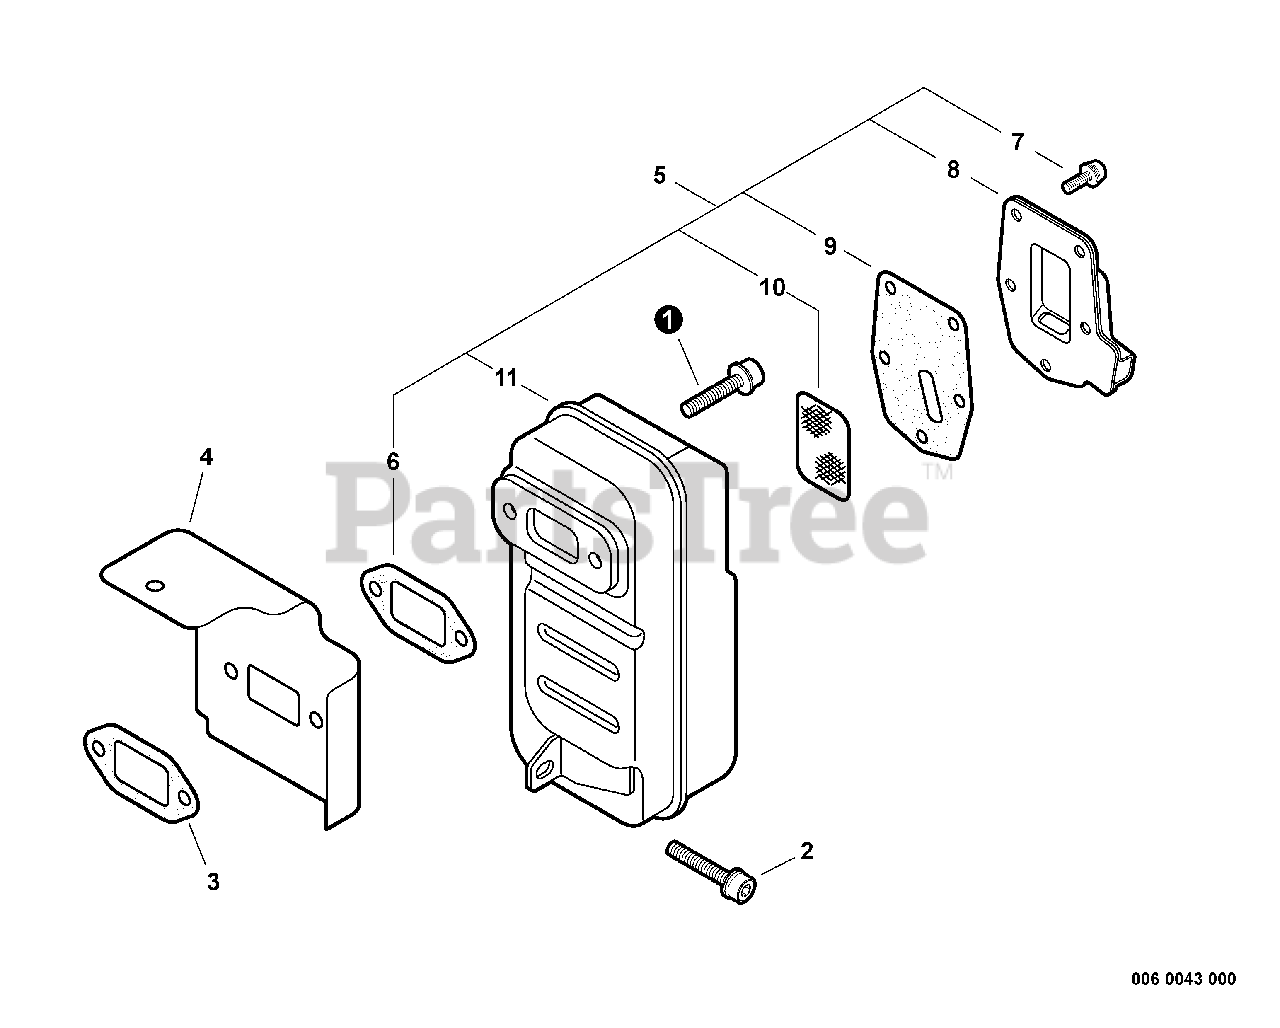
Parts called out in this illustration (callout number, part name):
1	SCREW - 6X20
2	SCREW - 5X20
3	GASKET, EXHAUST
4	COVER, CYLINDER
5	MUFFLER ASSY
6	GASKET, EXHAUST
7	SCREW - 4X10
8	GUIDE, EXHAUST
9	GASKET, EXHAUST
10	SCREEN, SPARK ARRESTOR
11	MUFFLER
